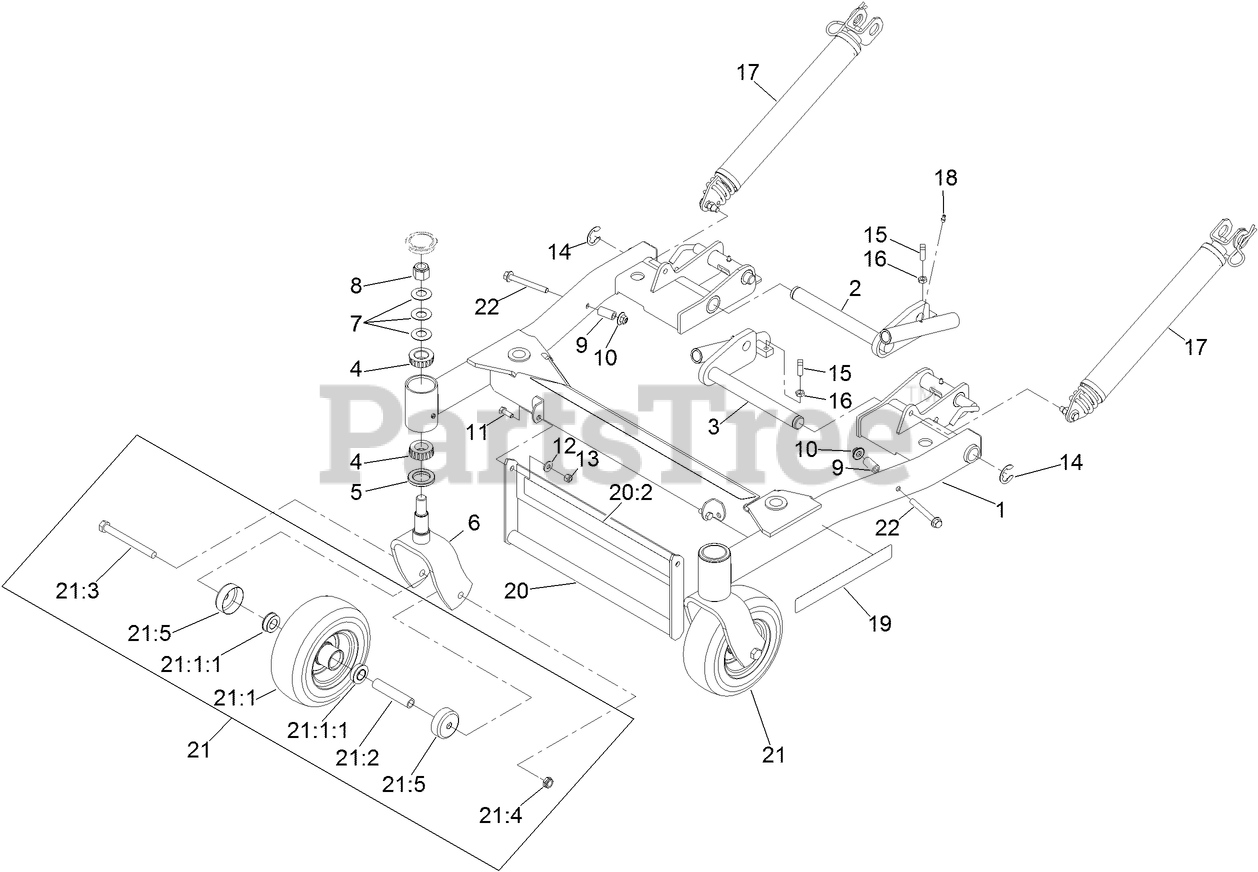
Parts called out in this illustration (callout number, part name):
1	FRAME-DECK SUPPORT W/DECALS
2	PIVOT-DECK, RH
3	PIVOT-DECK, LH
4	BEARING-ROLLER, TAPERED
5	SEAL-GREASE
6	FORK-CASTER
7	WASHER-BELLVILLE
8	NUT-LOCK, NI
9	SPACER
10	NUT-FLANGE, NI
11	SCREW-HH
12	WASHER-SPRING
13	NUT-LOCK, NI
14	RING-SNAP
15	SCREW-SET, SQH
16	NUT-JAM
17	LIFT ASSIST SPRING ASM
18	FITTING-GREASE
20	DECK LIFT HANDLE ASM
21	WHEEL AND AXLE ASM
21:1	WHEEL AND TIRE ASM
21:1:1	BEARING-BALL
21:2	SPACER-CASTER, FRONT
21:3	SCREW-HH
21:4	NUT-HEX
21:5	GUARD-SEAL
22	SCREW-HHF
